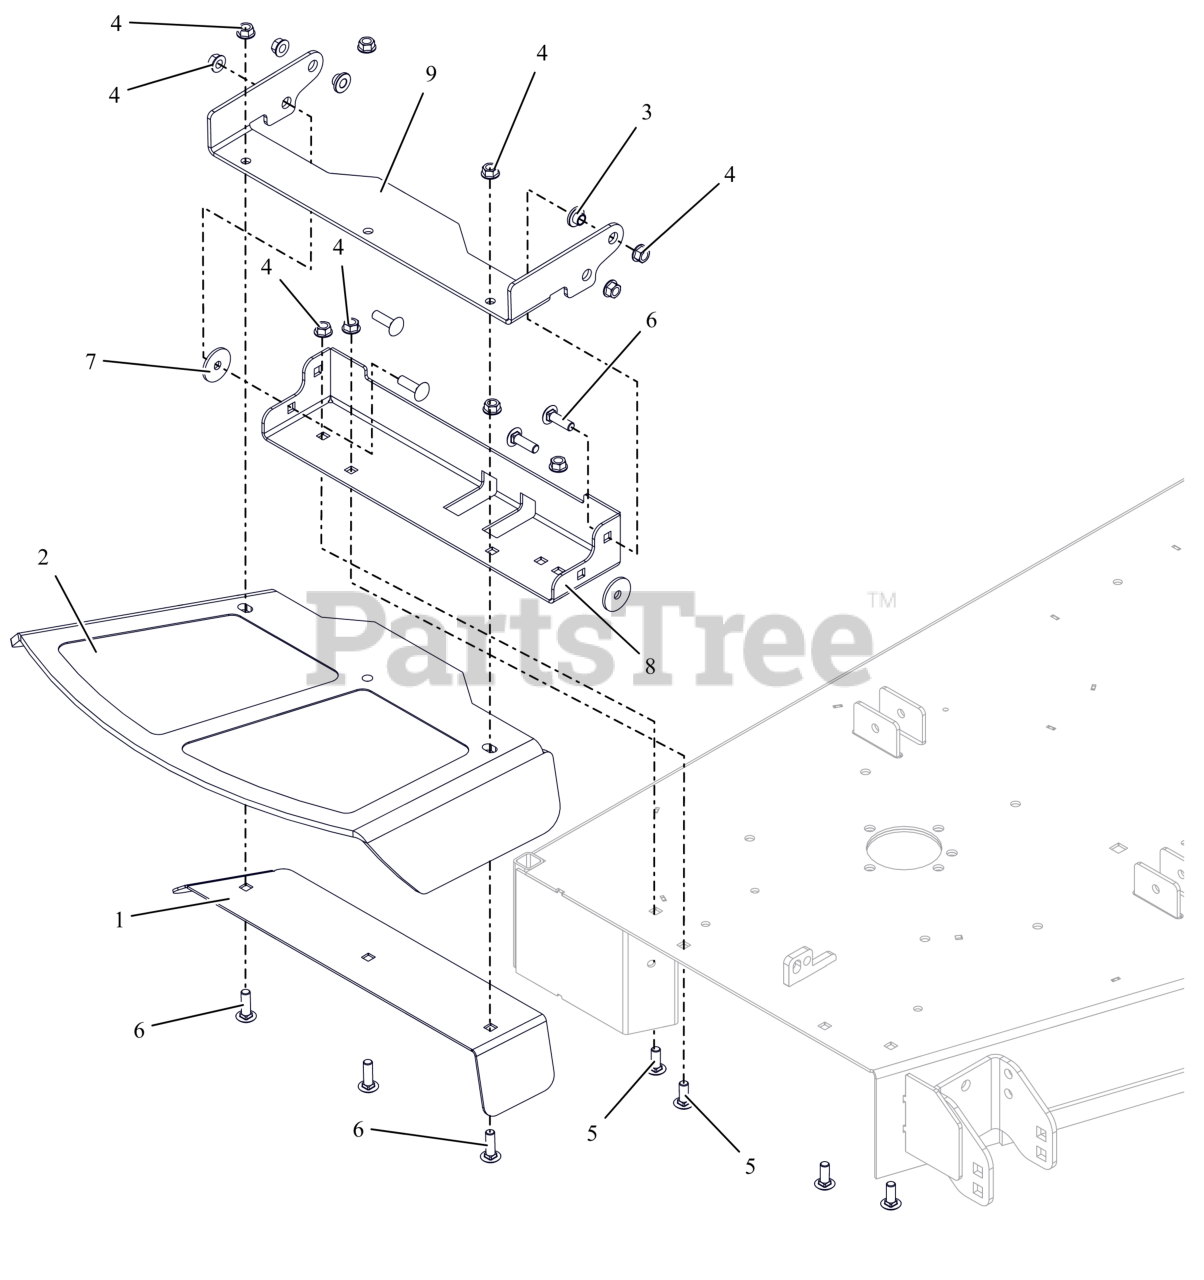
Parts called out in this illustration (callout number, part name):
1	PLT, DISCH. CHUTE CLMP-CE
2	CHUTE, FORMED RUBBER DISCHARGE
3	BSHG-FLG .385X.500X.875X.406
4	NUT-LK-CTR-FLG .375-16 GF ZCC
5	BLT,RHSSN .38-16X1.00 G5 ZCC
6	BLT,RHSSN .38-16X1.25 G5 ZCC
7	WSHR, FLT .380X1.50X.125 ZCC
8	WMT, DISCH. CHUTE-CE-W/SAFETY
9	BRKT, CE CHUTE MTG
